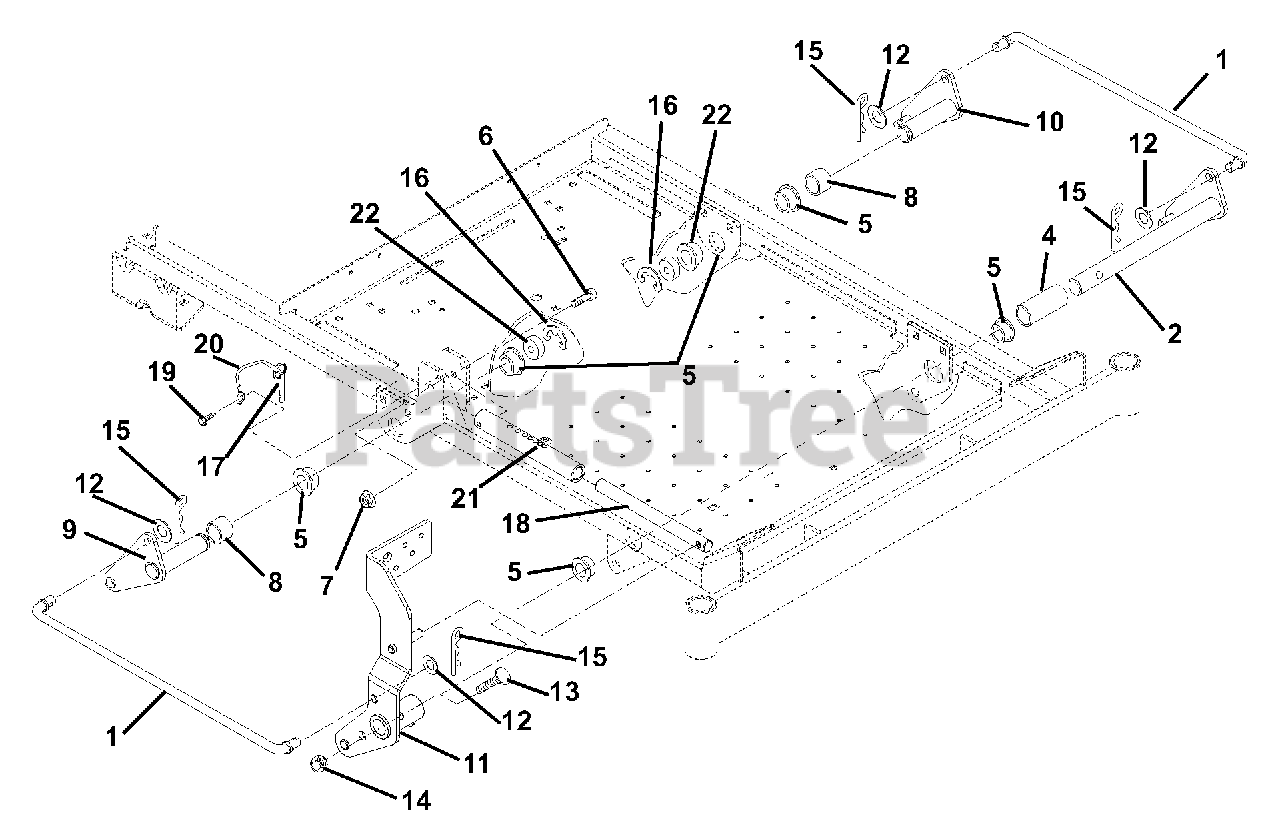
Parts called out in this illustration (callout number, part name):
1	ROD, LIFT
2	WELDMENT,FRONT LIFT
3	TRUNNION-.50
4	BSHG, SPCR 1.01X1.25X2.63 PM
5	BSHG-FLG 1.000X1.12X.62X1.50BR
6	BLT, SKH SHLD .31X18X2.00
7	@NUT-LK-NYL-FLG .31-18 YWZC
8	BSHG-SPCR 1.032X1.250X.88 PM
9	WELDMENT, LIFT, REAR - RH
10	WELDMENT, LIFT, REAR - LH
11	WMT, FOOT PEDAL
12	@WSHR-FL-STL.531X1.06X.095YWZC
13	@BLT-HEX .38-16X2.00 GR5 YWZC
14	@NUT-LK-NYL-FLG .38-16 YWZC
15	PIN, HAIR, EXT - #16 YWZC
16	RG-RTNG .822X1.500X.050 TYP E
17	PIN, SPRING BALL .375OD X 1.50
18	ROD, LIFT
19	@SCR-TAP .25-20X.37 HWH YWZ TR
20	CBL,HOOD
21	TUBE, LIFT STOP
22	BSHG, SPCR 1.032X1.25X.25 PM
